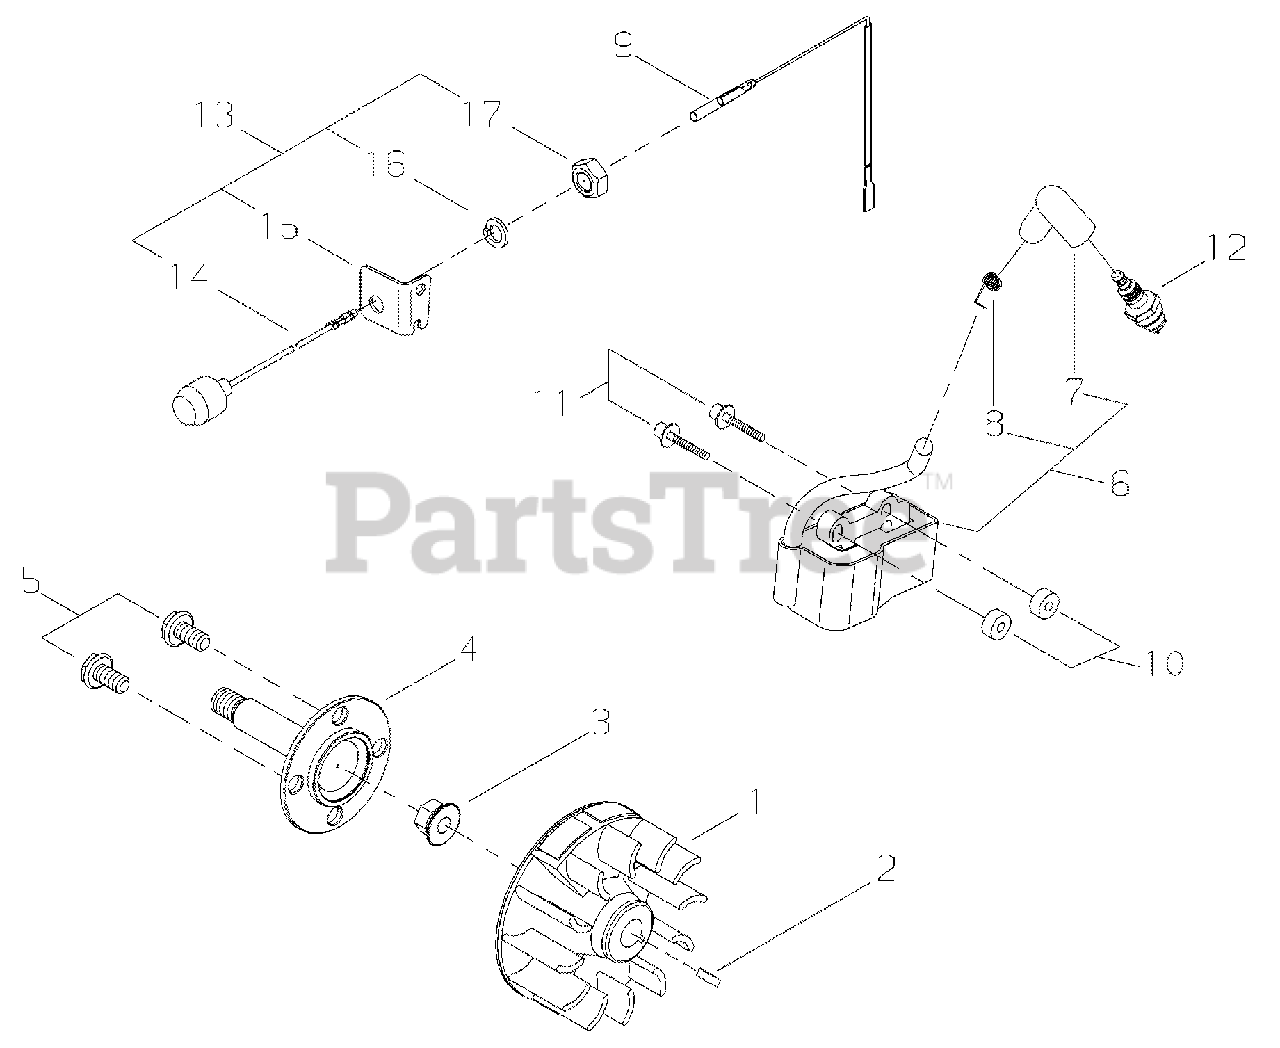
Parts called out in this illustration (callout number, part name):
1	FLYWHEEL Ø95
2	KEY, WOODRUFF 3×10
3	NUT M8
4	SHAFT, PUMP
5	BOLT, FLANGE M8×16
6	COIL ASSY, IGNITION
7	CAP, SPARK PLUG
8	TERMINAL, SPARK PLUG
9	LEAD - IGNITION L= 220 MM
10	INSULATOR 4.2×11×6
11	BOLT M4×26
12	SPARK PLUG - CMR5H
13	SWITCH ASSY, STOP W/BRACKET
14	SWITCH, IGNITION
15	BRACKET
16	LOCKWASHER
17	NUT
